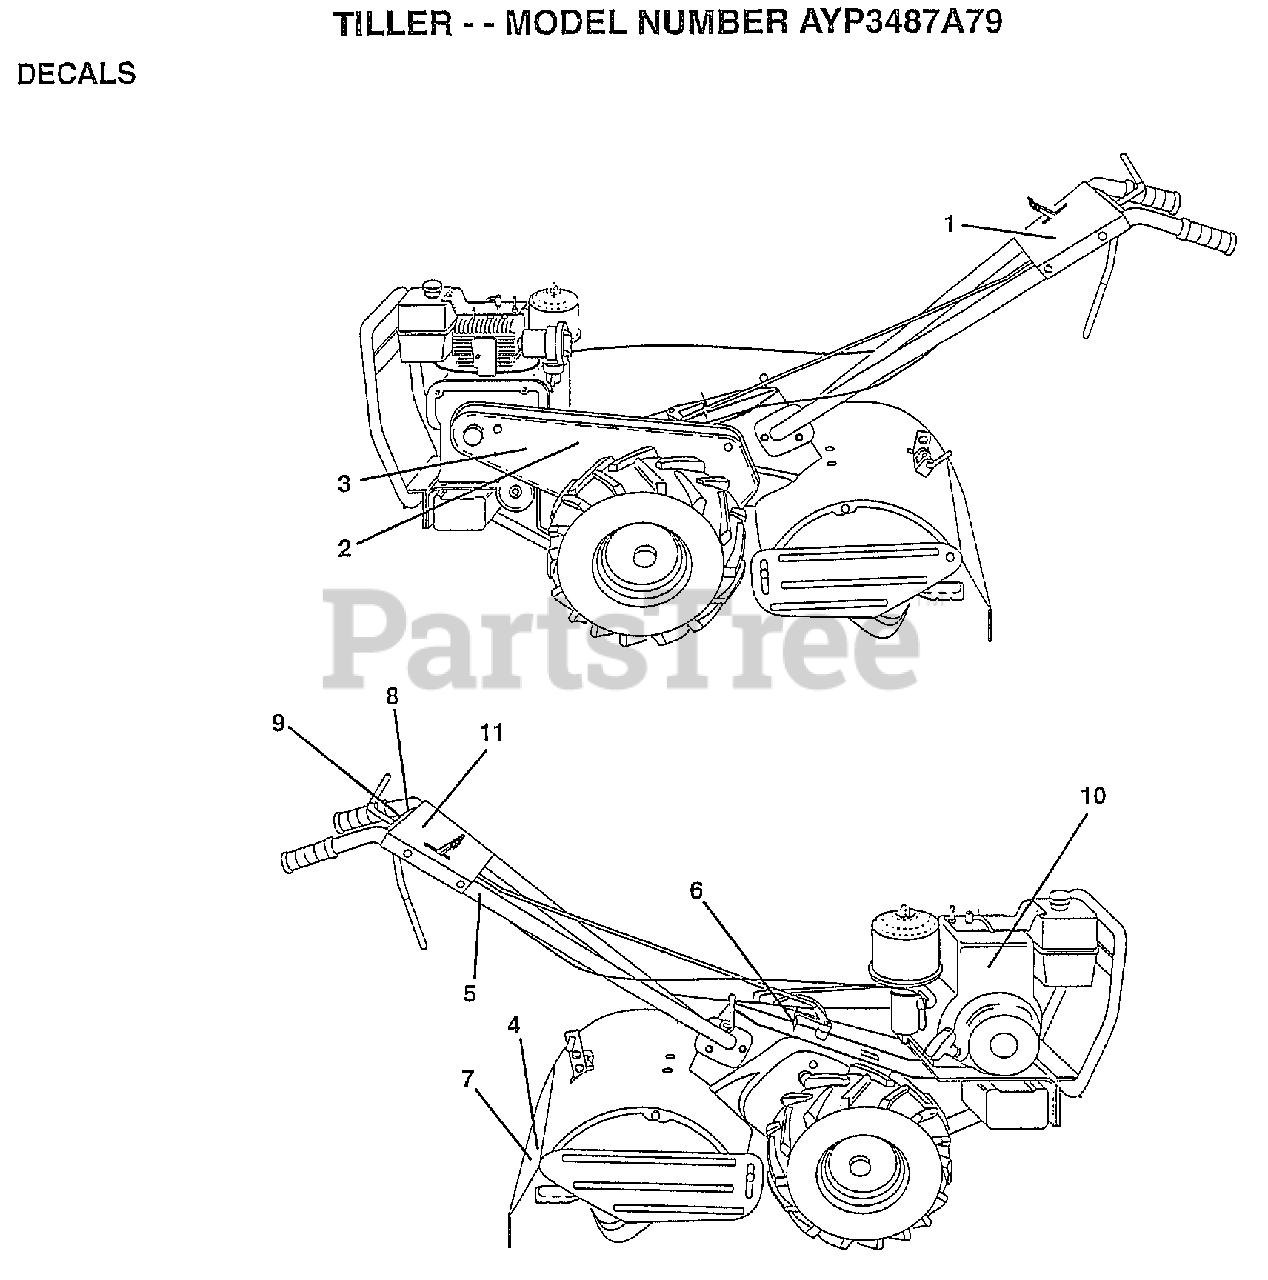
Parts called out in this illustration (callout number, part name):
1	DECAL.CNTL.PNL.WZ
3	DECAL.GUARD.BLT.W
5	DECAL TI
6	DECAL.SHIFT.IND.
7	DECAL TI
10	DECAL, BRIGGS & STRATTON
11	DECAL.PANEL 8 HP
